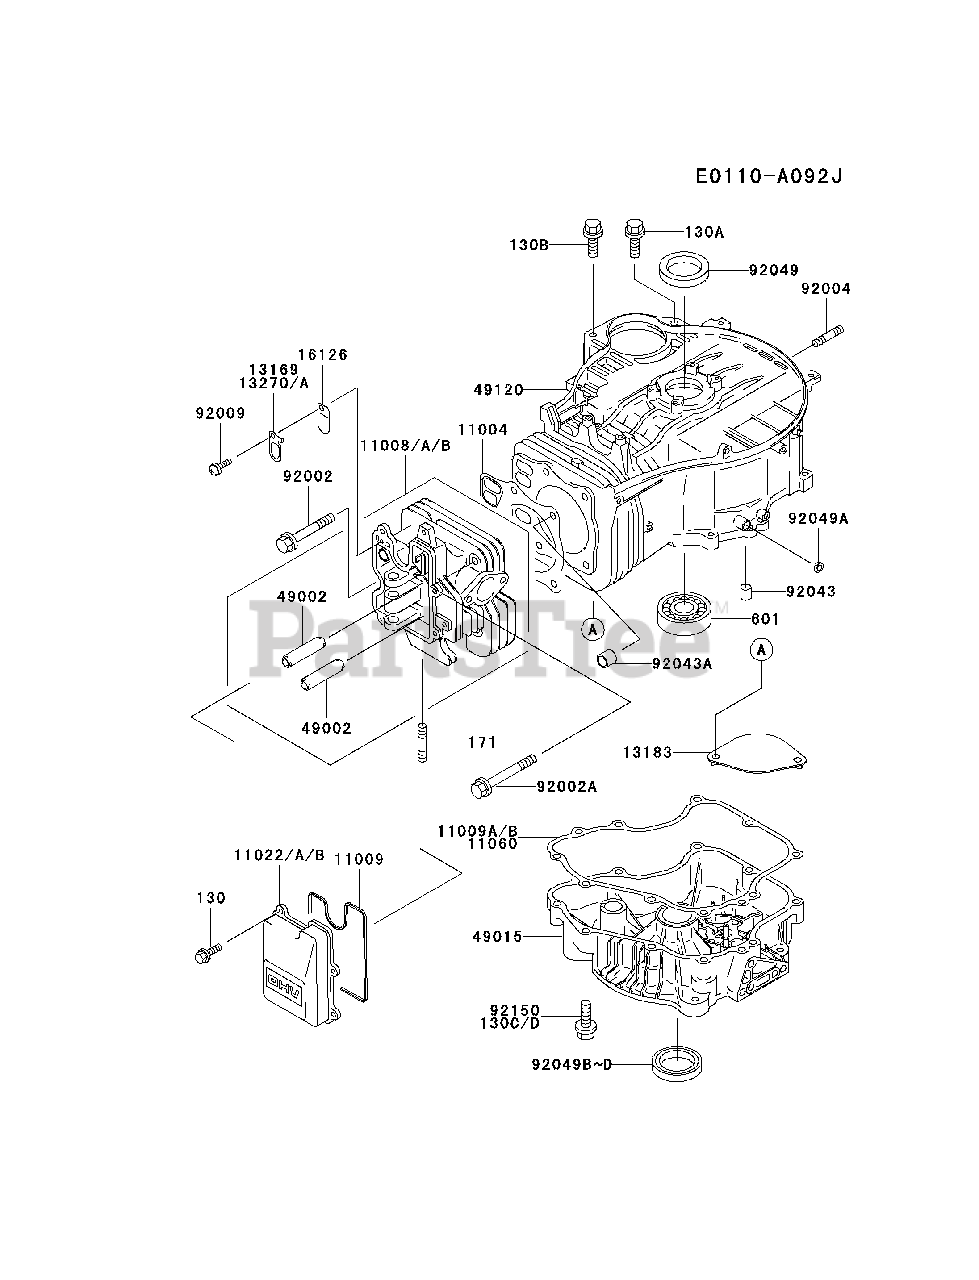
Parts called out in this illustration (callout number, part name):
130A	BOLT-FLANGED
130B	BOLT-FLANGED
130D	BOLT-FLANGED
171	BOLT-STUD
601	BEARING,BALL
